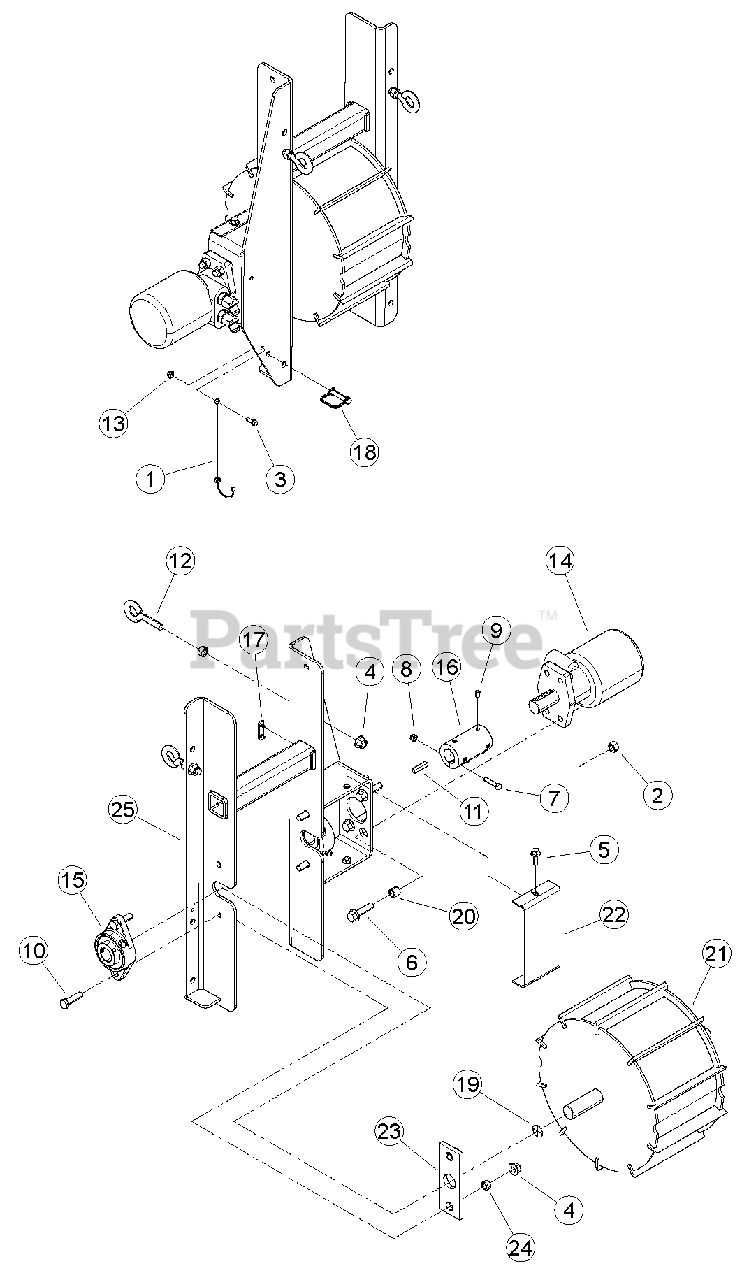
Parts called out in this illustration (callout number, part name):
1	LANYARD, NYLON
2	NUT, 1/2" CENTERLOCK GRB ZP
3	BOLT, 1/4-20 X 3/4 HWH GR5 CZP
4	NUT, 1/2-13 NYLOCK FLANGE
5	BOLT, 3/8 X 1 FLANGE NC
6	BOLT, 1/2-13 X 2 HWH GR5 CZP
7	BOLT, 5/16 X 1-1/2 GR5 HEX CPS ZP
8	NUT, 5/16" NE NYLOCK ZP
9	SET SCREW, 3/8 X 1/2 CUP PT SKT
10	BOLT, 1/2 X 1-3/4 GR5 HCPS NC ZP
11	KEY, 5/16 X 1-1/2 SQUARE
12	EYEBOLT, 1/2 X 2" ZP
13	NUT, 1/4-20 NYLOCK-FLANGE
14	MOTOR, 45 CU IN HYDRAULIC
15	BEARING, 1-1/4" DIA 2 BOLT FLANGE
16	COUPLER, 1-1/4 SHAFT
17	WEAR PAD, STD. SPRING HD FRONT
18	PIN, SNAP 3/8 X 1-1/2 USABLE LGH
19	DECAL, ROTATING SHAFT
20	SPACER, 0.75 X 0.620
21	WELDMENT, TOP GRAB ROLLER
22	SHIELD, COUPLER
23	BEARING, SLIDE
24	SPACER, .75 OD X .5 ID X .37
25	WELDMENT, ROLLER SLIDE
